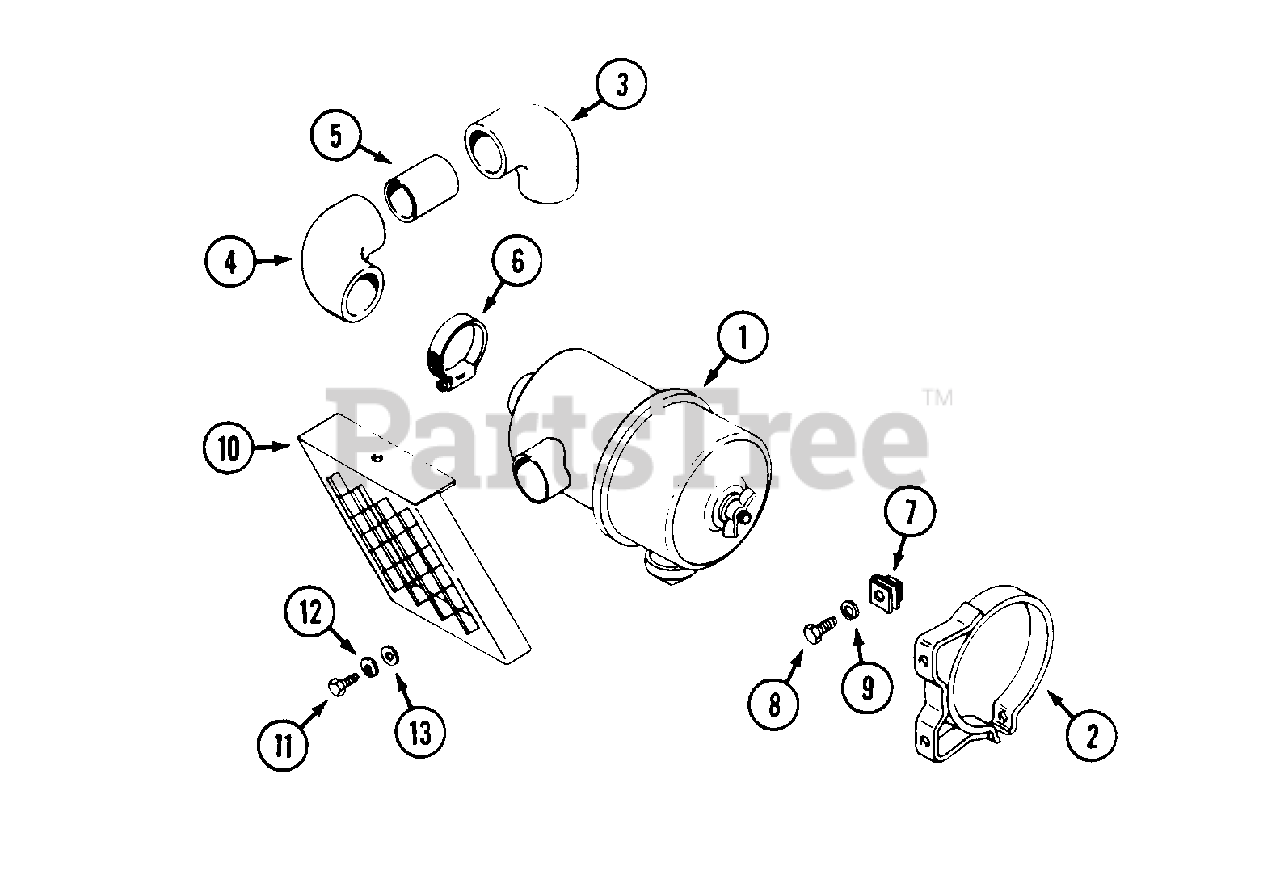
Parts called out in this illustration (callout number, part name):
1	AIR CLEANER ASSEMBLY
2	BRACKET - air cleaner
3	HOSE - engine
4	HOSE - air cleaner
5	TUBE - air
6	CLAMP - hose
7	NUT - "J" 1/4" - 20
8	BOLT - 1/4" - 20 x 5/8"
9	LOCKWASHER - 1/4"
10	INTAKE - air
11	BOLT - 1/4" - 20 x 1/2"
12	LOCKWASHER - 1/4"
13	WASHER - 1/4"
